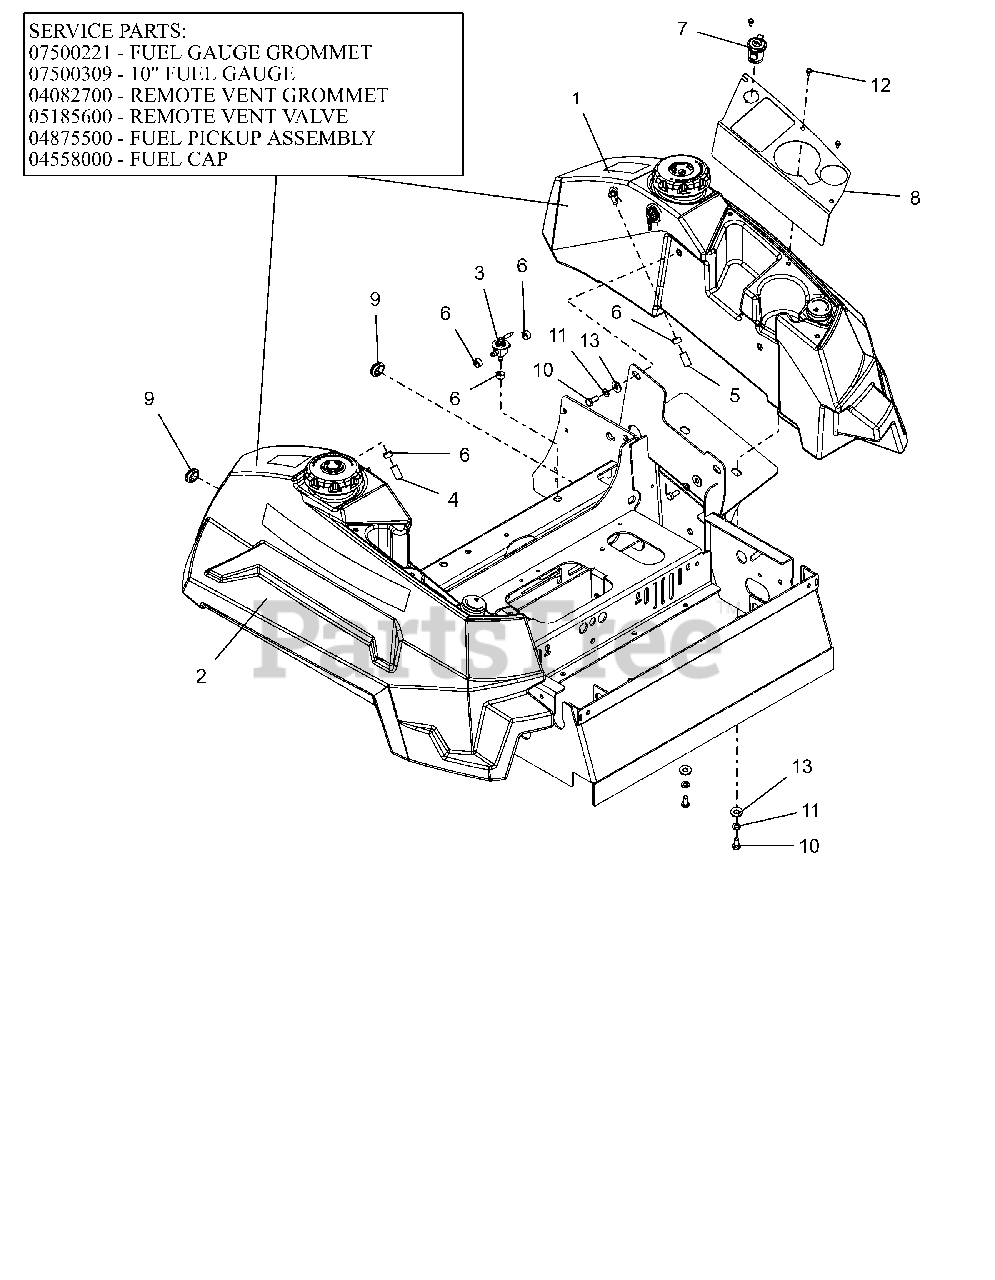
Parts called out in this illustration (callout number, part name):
1	ASM, LH FUEL TANK
2	ASSY-RH, PT400 FUEL TANK
2	GROMMET, FUEL GAUGE
2	GAUGE, REMOTE FUEL SEALED 10"
2	GROMMET, REMOTE VENT NITRILE
2	VALVE, COMBINATION VENT 3/16
2	ASSM,LRG TANK FUEL PICKUP LINE
2	CAP, FUEL VENTIN AUTOLOCK
3	VALVE - FUEL
4	HOSE, .25 LOW-PERM BULK GAS
5	HOSE, .25 LOW-PERM BULK GAS
6	CLAMP, FUEL LINE
7	PORT, 12 VOLT POWER
8	CUP HOLDER/POCKET PLATE - RED
9	GROMMET,RUBBER 5/8 ID/1.13 OD
10	@BLT-HEX .31-18X.75 GR5 YWZC
11	@WSHR-LK .31X.078 REG YWZC
12	SCR-MCH 10-24X.38 HWHSTAINLESS
13	@WSHR-FL-STL.38X.875X.083 YWZC
